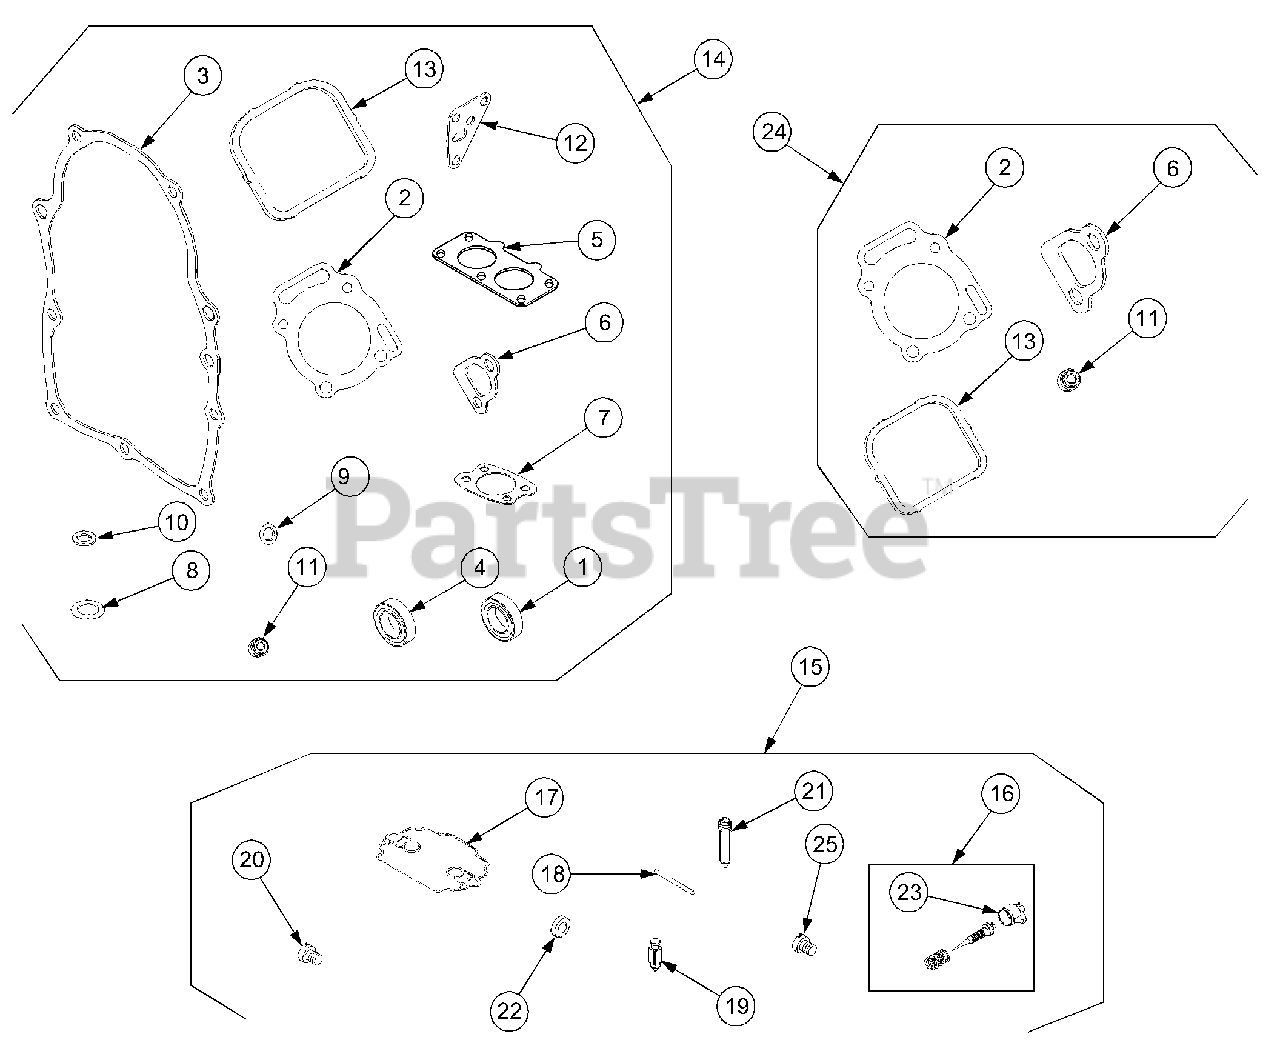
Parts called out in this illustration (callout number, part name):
1	Seal, Oil (Magneto Side)
2	Gasket, Cylinder Head
3	Gasket, Crankcase
4	Seal, Oil (PTO Side)
5	Gasket, Intake
6	Gasket, Intake
7	Gasket, Air Cleaner
8	Seal, O-Ring (Oil Pump)
9	Seal, O-Ring (Crankcase Cover)
10	Seal, O-Ring (Oil Pump Screen)
11	Seal, Valve
12	Gasket, Oil Adapter
13	Gasket, Rocker Cover
14	Gasket Set, Engine
15	Kit, Carburetor Overhaul
16	Kit, Idle Mixture
17	Gasket, Carburetor Body
18	Pin, Float Hinge
19	Valve, Float Needle
20	Jet, Main (Standard) Cylinder #1
21	Nozzle, Carburetor
22	Seal, Choke/Throttle Shaft
23	Cap, Limiter
24	Gasket Set, Valve
25	Jet, Main (Standard) Cylinder #2
